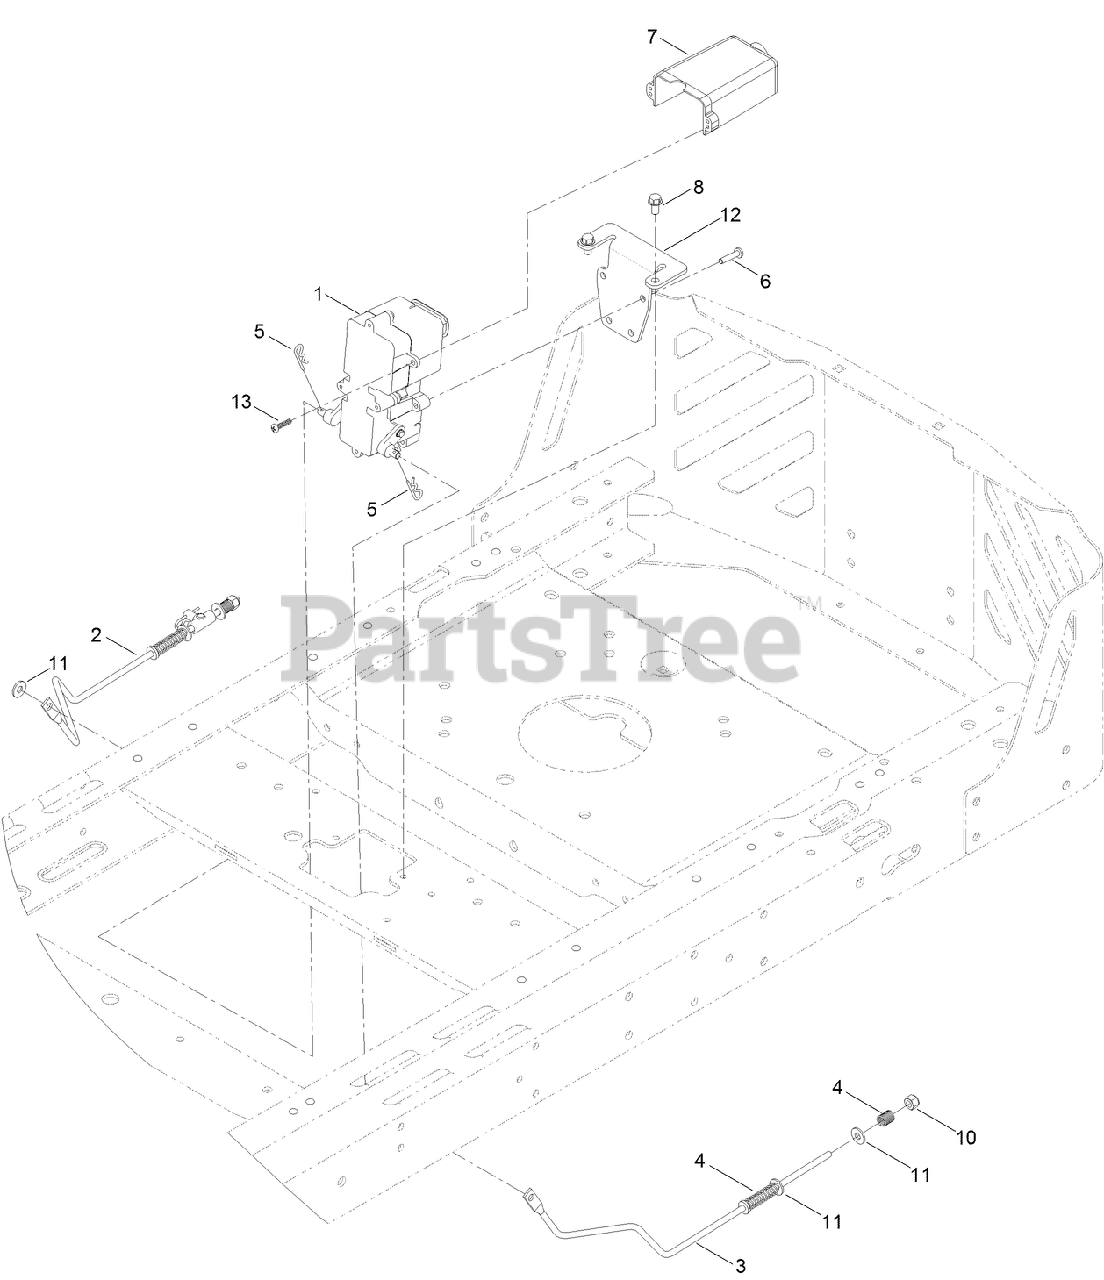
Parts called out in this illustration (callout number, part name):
2	ROD-BRAKE, RH
3	ROD-BRAKE, LH
4	SPRING-COMPRESSION
6	SCREW-PPH
8	SCREW-HWH
10	NUT-LOCK, NI
11	WASHER
12	BRACKET-MOUNT, BRAKE
13	SCREW-PPH
